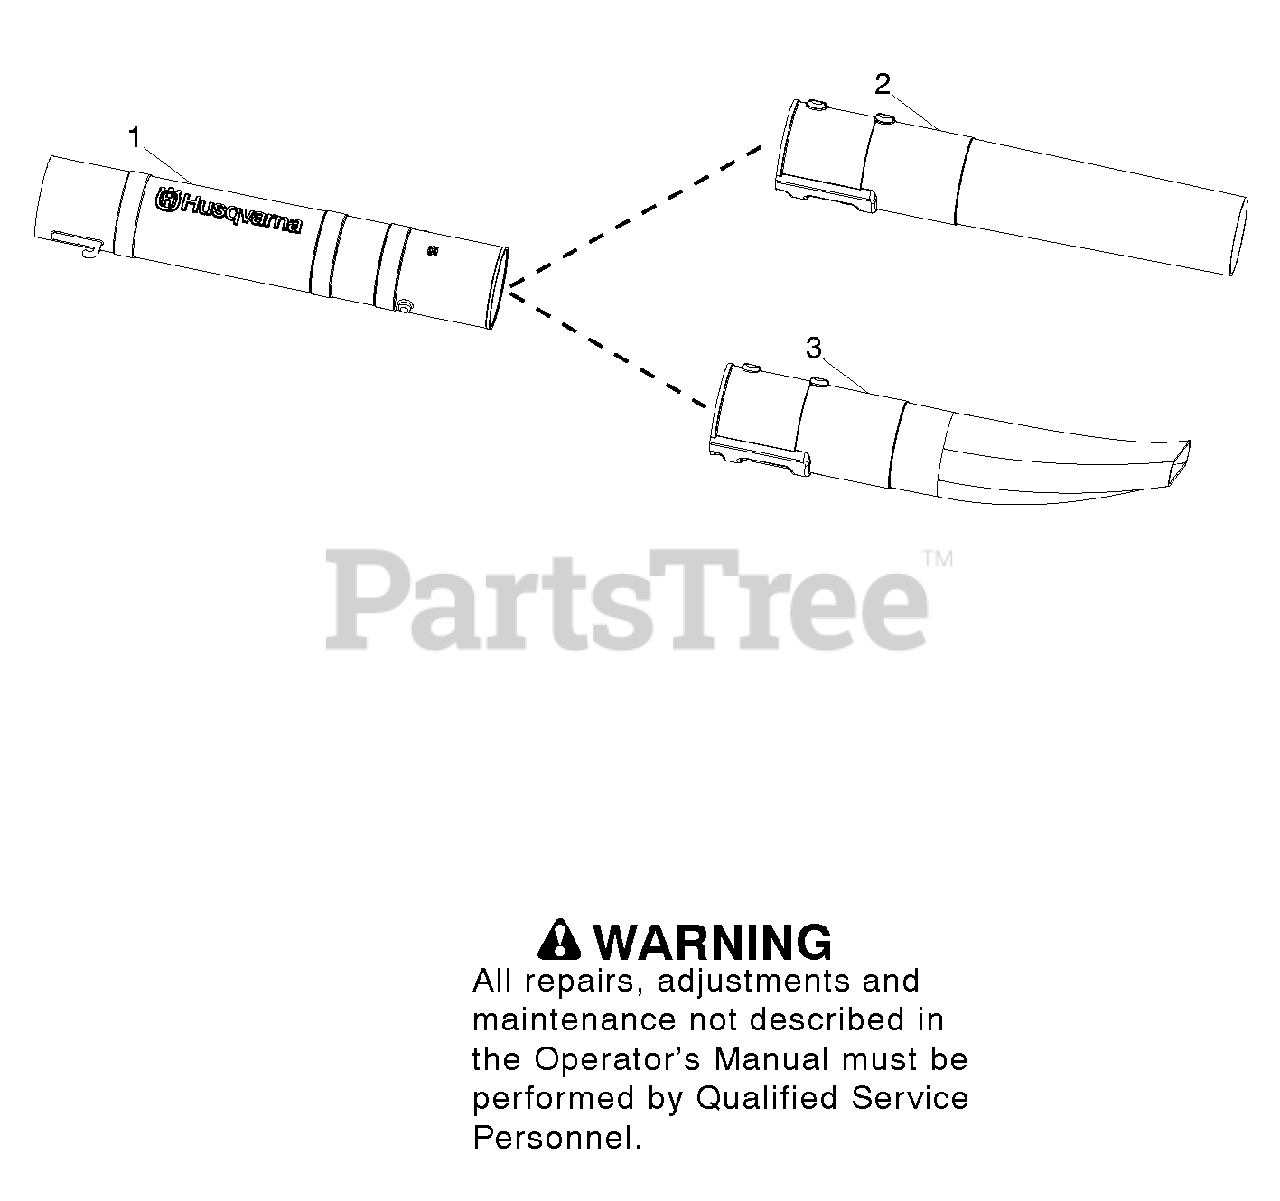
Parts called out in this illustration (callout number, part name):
1	Assy - Tube - Upper Blower w/barrier
2	Tube - Lower Blower
3	Tube - Lower Blower Flare
